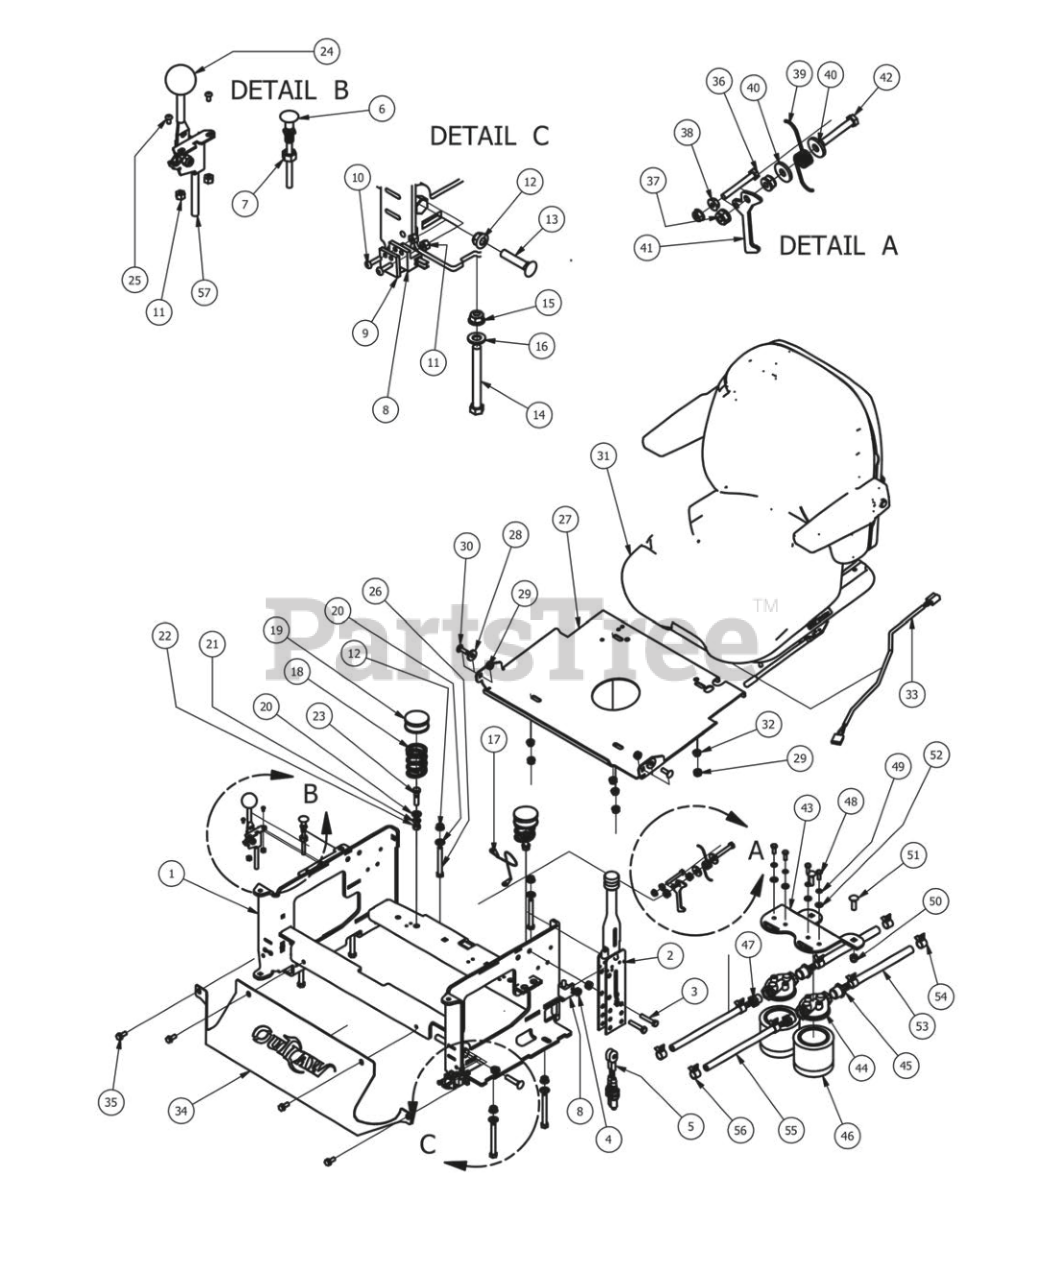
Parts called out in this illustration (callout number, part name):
1	Outlaw Seat Bracket 2012
2	Hand Brake
3	5/16" x 1 3/4" Hex Bolt
4	5/16-18 Nylon Flange Nut
5	Long Brake Cable
7	3/8" Fine eaded Jam Nut
8	Safety Switch
9	Switch Block Plastic
10	10-24 x 1 BS C/S 18-8 SS
11	10-24 Nylon Insert Locknut
12	3/8" Nylock Flange Nut
13	3/8 x 1 3/4 Carriage Bolt
14	3/8-16x3-1/2 grade 5 hex bolt
15	3/8" Nylock Flange Nut
16	3/8" Flat Washer
17	Seat Cable
18	Seat Spring
19	Spring Cap Cover
20	3/8" Flat Washer
21	3/8" Lock Washer
22	3/8" Hex Nut
23	3/8" x 1 1/2" Hex Bolt
24	Universal Throttle Head - 2012
25	10-24 X 5/8 BS C/S 18-8 SS
26	3/8-16x3 grade 5 hex bolt
27	2006 Seat Plate
28	.360 ID Plastic Washer
29	5/16-18 Nylon Flange Nut
30	5/16" x 1" Carriage Bolt
31	2010 Outlaw Seat
32	5/16" Flange Nut
33	Seat Switch Adapter
34	Outlaw Cooler Cover
35	5/16 x 3/4 washer head type F screw
36	1/4-20 x 2 Hex Bolt
37	5/16-18 Nylon Flange Nut
38	1/4-20 Hex Flange Nuts Zinc w/Serrations
39	Torsion Spring for Seat latch
40	.360 ID Plastic Washer
41	Seat Latch Lever
42	5/16-18 X 2 Hex C/S (GR.5) ZC
43	Outlaw Filter Bracket
44	Filter Head-Hydraulic Filter
45	Filter Head Fitting 1/2 x 1/2
46	Hydraulic filter
47	1/2" Pipe to 3/8" Barb
48	1/4" x 3/4" Hex Bolt
49	1/4" Lock Washer
50	3/8 Nylock Nut
51	3/8" x 1 1/4" Carriage Bolt
52	1/4" Flat Washer
53	1/2 Clear Braded Hose Priced/Foot
54	1/2 Hose Clamp
55	3/8 clear hose price per foot
56	3/8 hose clamp
57	Outlaw Throttle Cable Only
